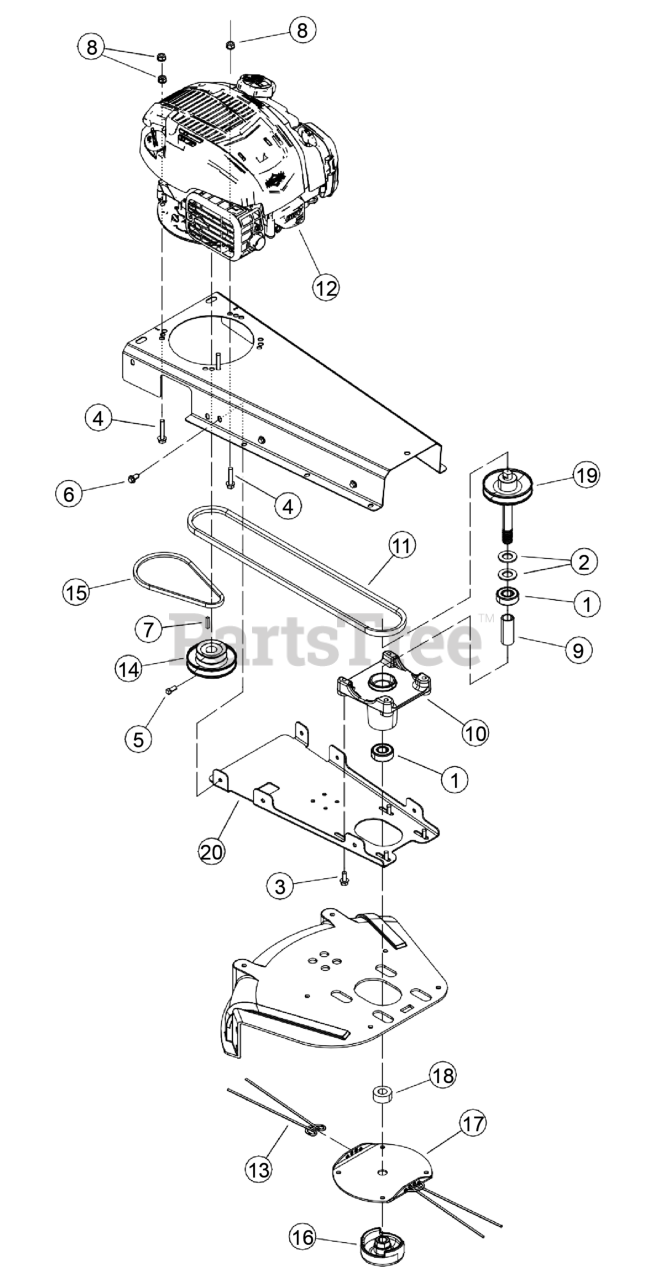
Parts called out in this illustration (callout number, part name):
1	BEARING, 3/4 BALL
2	WASHER, 3/4" SAE FLAT ZP
3	BOLT, 5/16 × 3/4 FLANGE NC
4	BOLT, 5/16 × 1-1/2 FLANGE NC
5	SCREW, 5/16-18 × 5/8 SQ HD SET
6	SCREW, 11/32-12 × 7/8 FLANGE T-AB
7	KEY, 3/16 SQ X 1.75
8	NUT, 5/16-18 NYLOCK FLANGE
9	SPACER, TRIMMER SPINDLE
10	CASTING, TRIMMER SPINDLE HUB
11	BELT, AX48
12	STRAP,11 IN BLACK TIE
13	STRAP,11 IN BLACK TIE
14	PULLEY, 4.0/2.5 X .875
15	BELT, 3L220
16	MOWBALL, CAST TRIMMER PAINTED
17	DISK, TRIMMER HEAD
18	SPACER, TRIMMER HEAD
19	WELDMENT, SPINDLE HW MODELS
20	PLATE, HWS SPINDLE CASTING MOUNT
